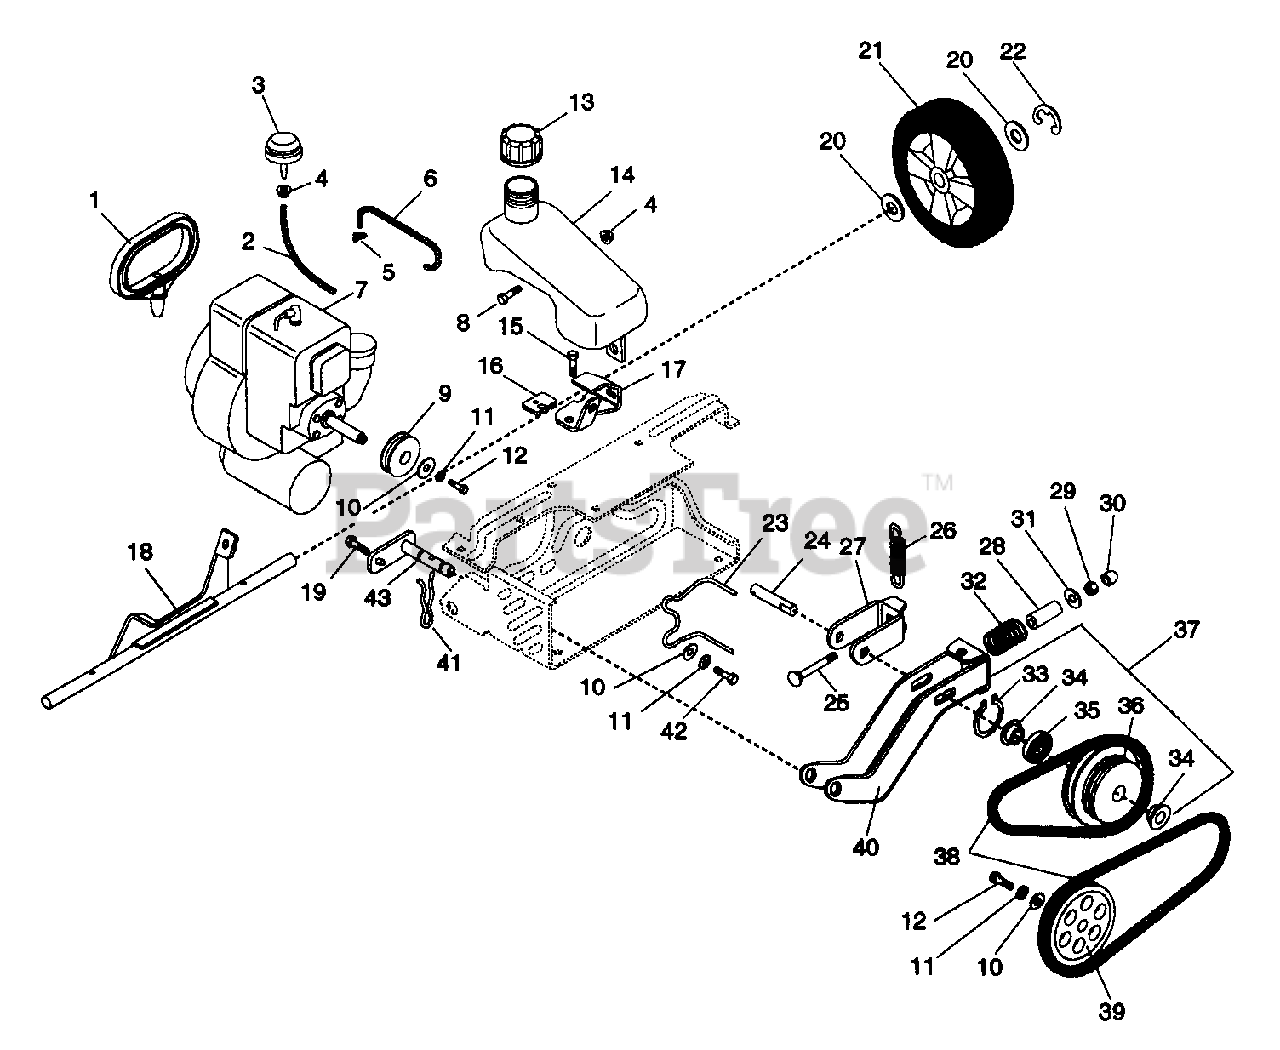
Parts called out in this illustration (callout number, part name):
1	HANDLE, RECOIL START
2	PRIMER LINE
3	PRIMER ASSY
4	NUT-LK-FLG .250-20 PL BLK
5	CLAMP-HOSE WIR.490/.510X.092#8
6	FUEL LINE
7	ENGINE 3HP 2 CYCLE
8	BLT-HEX .25-20X.50 PL GR2
9	SHEAVE HALF - ENGINE
10	WSHR-FL-STL .328X.875X.062 PL
11	WSHR-LK .313X.078 PL MED
12	BLT-HEX .31-24X.50 GR5
13	FUEL CAP-2 CYCLE BLACK
13	FUEL CAP 2 CYCLE ORANGE
14	FUEL TANK
15	SCR-TAP .312-18X.50 HWH PL TR
17	TANK BRACKET
18	AXLE WELDMENT
19	BLT-SERHFWH .25-20X.50 PL
20	WSHR-FL-STL .531X.938X.104 PL
21	T/WHL ASSY
22	RG-RTNG-EXT .500X.042 (E)
23	BELT FINGER
25	BLT-RDHDSQNK .31-18X3.25 FTHPL
26	SG-TENS .080X.80X2.48 WLD 6
27	TENSION BRACKET
28	SPACER .400X.530X1.120
29	NUT-LK-NYL.312-18 PL
30	CAP, VINYL, .25 ID
31	WSHR-FL-STL .328X1.0X.094 PL
32	SG-COMP .148X.87X1.50
33	RG-RTNG-INT 1.620X.062
34	BSHG-FLG .504X.670X.640X.900
35	BRG-BALL .669X1.575X.47 (6203)
36	SHEAVE-ALUM
37	PULLEY ASSEMBLY
38	V-BELT, 3L-RAW EDGE
39	SHEAVE HALF - IMPELLER
40	BRACKET - PIVOT
41	PIN-HAIR-EXT .062X.38X1.00
42	BLT-HEX .31-18X.75 PL GR2
42	BLT-HEX .31-18X1.00 PL GR 2
43	PIN & PLATE ASSY
